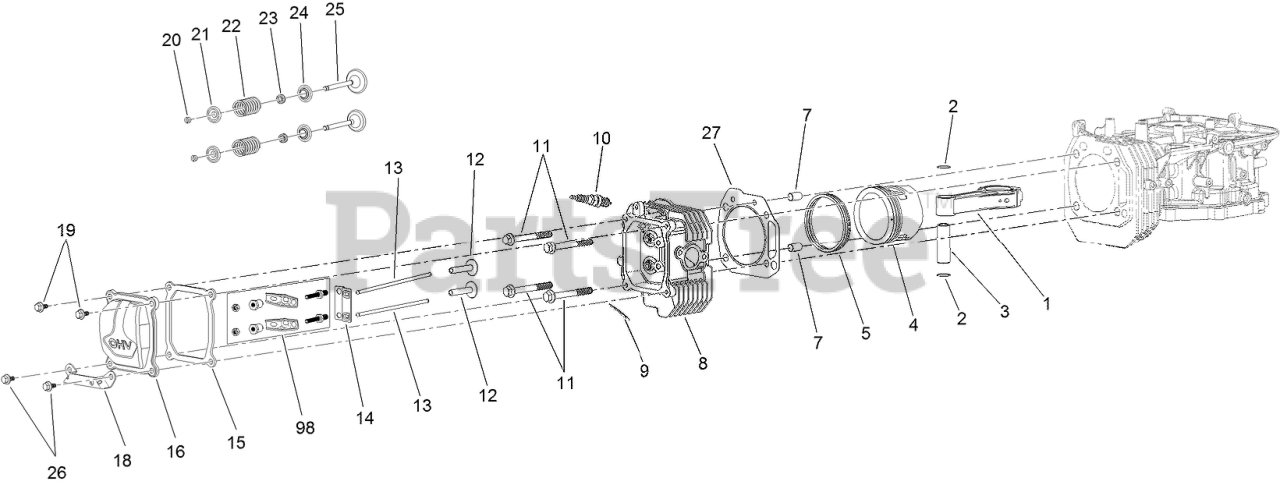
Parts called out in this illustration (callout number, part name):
1	CONNECTING ROD ASM
2	RING-RETAINING, PISTON PIN
3	PIN-PISTON
4	PISTON
5	RING SET
7	PIN-DOWEL
8	HEAD-CYLINDER
9	GASKET-EXHAUST
10	PLUG-SPARK
11	SCREW-HHF
12	LIFTER-VALVE
13	ROD-PUSH
14	PLATE-GUIDE, PUSH ROD
15	GASKET-COVER, VALVE
16	COVER-VALVE
18	BRACKET-MUFFLER
19	SCREW-SHOULDER, HHF
20	KEEPER-VALVE
21	RETAINER-SPRING, VALVE
22	SPRING-VALVE
23	SEAL-STEM, VALVE
24	SEAT-SPRING, VALVE
25	VALVE SET
26	SCREW-SHOULDER, HHF
27	GASKET-CYCLINDER
98	ROCKER ARM KIT
